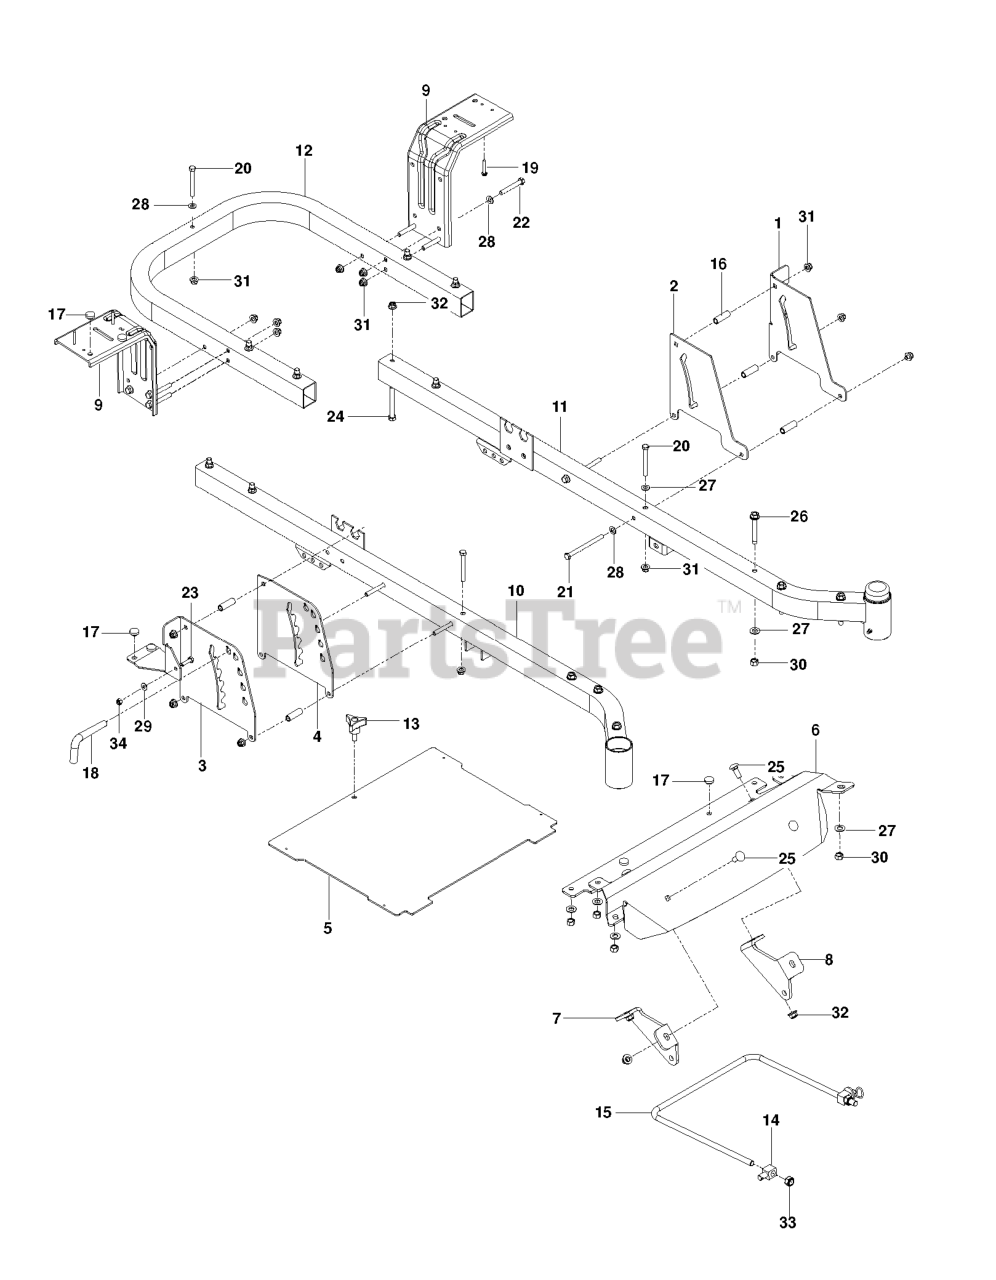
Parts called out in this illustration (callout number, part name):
1	PLATE, OUTER BRAKE, BLACK
2	PLATE, BRAKE LATCH, BLACK
3	PLATE.DECK HEIGHT.PNT.431.RZ
4	PLATE, DECK HEIGHT, BLACK
5	PLATE, FOOT W/DECALS RZ
6	FOOT.REST.MED.ORANGE
7	MOUNT, STRUT, RT, BLK
8	MOUNT, STRUT, LT, BLK
9	SUPPORT, FENDER, BLACK
10	FRAME, RT, ORANGE
11	FRAME, LT, ORANGE
12	FRAME TUBE, REAR ORG
13	KNOB W/STUD
14	SWIVEL
15	LINK, FRONT SUSP.
16	SPACER.334.ID.5.OD.1.5.L
17	GROMMET, BUMPER
18	PIN.DECK.HEIGHT.RZ
19	SCR #10-12X1-1/2HEX WASH HD ZD
20	BOLT HEX
21	BOLT
22	BOLT.FIN HEX 5/16-18UNC X2 1/4
23	BOLT
24	BOLT.HEX.FIN.3/8-16 X 3.GR5
27	RP WASHER 3/8 FLAT
28	WASHER
29	WASHER
30	NUT HEX 3/8-16 NYLON, THIN
31	5/16-18 NYLOC FLANGE NUT
32	NUT 3/8-16 HEX FLG NYLOC ZD
33	7/16-14 HEX NUT W/NYL RING ZD
34	LOCKNUT.NYLOC.1/4-20
